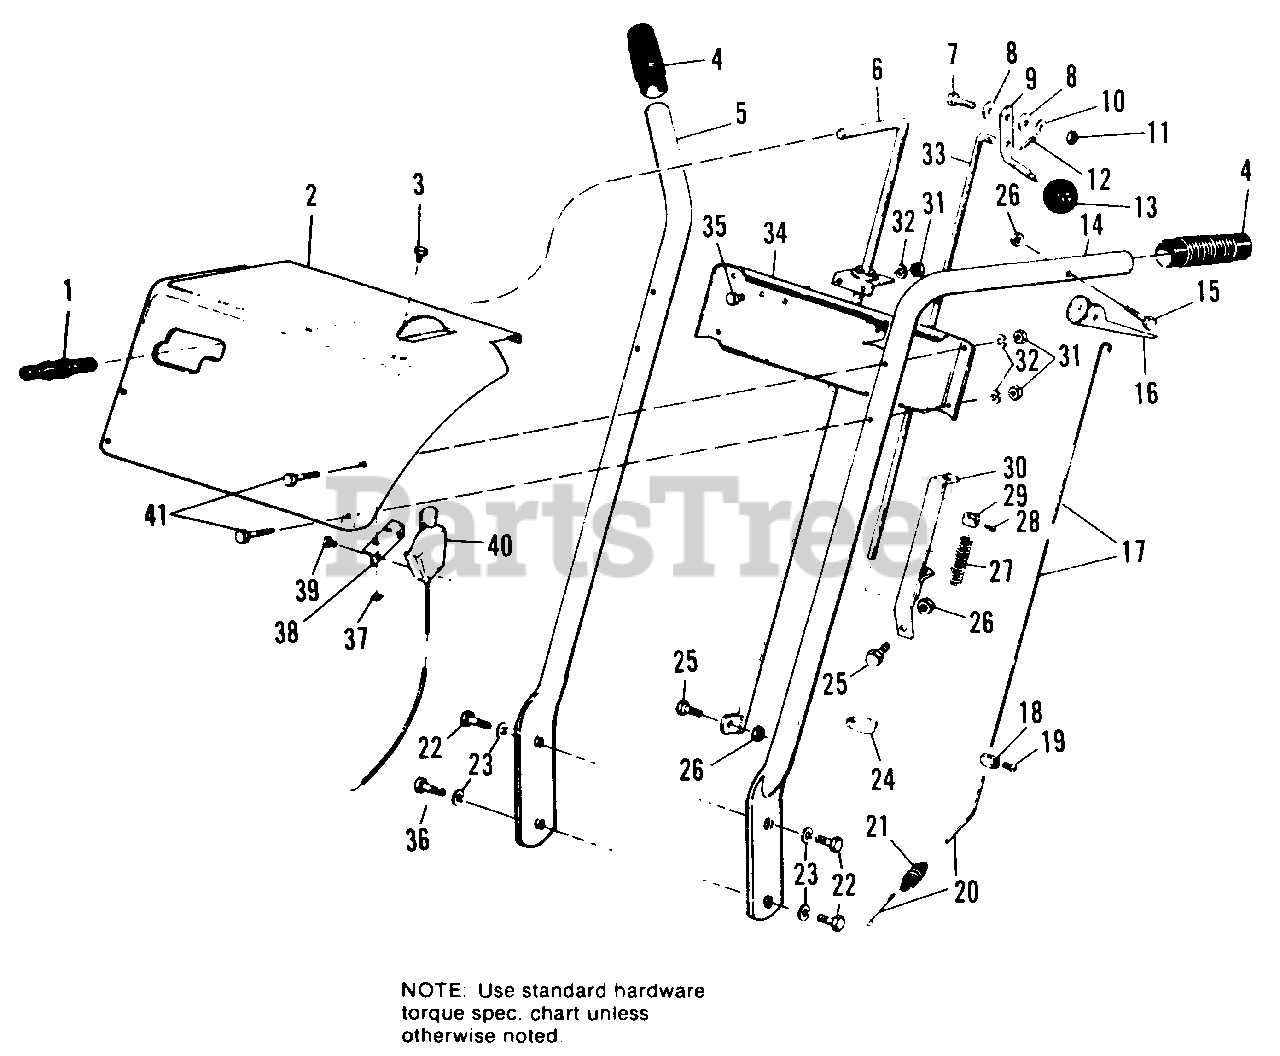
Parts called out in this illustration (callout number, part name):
1	GRIP, Handle
2	HOUSING ASSY., Control (990372 & 990430 Only)
2	HOUSING ASSY., Control (990560 Only)
3	SCREW, Self Tapping, #10 x 1/2 (990372 & 990430 Only)
3	SCREW, Self Tapping, 1/4 x 20 x 1/2 (990560 Only)
5	HANDLE, R.H. (990430 & 990560 Only)
5	HANDLE, R.H. (990372 Only)
6	ROD ASSY., Shift
7	CAPSCREW, Hex, 5/16-18 x 7/8
8	WASHER, Nylon
9	HANDLE, Clutch
10	WASHER, Plain, 1/4
11	LOCKNUT, Hex, W/Nylon Insert, 5/16-18
12	PIN, Cotter, 3/32 x 3/4
14	HANDLE, L.H. (990430 & 990560 Only)
14	HANDLE, L.H. (990372 Only)
15	CAPSCREW, Hex, 1/4-20 x 1-3/4
16	GRIP, Clutch
17	EXTENSION, Spring
18	CLAMP, Wire
19	SCREW, Rd. Hd., #10-24 x 3/8
20	EXTENSION, Wire
22	CAPSCREW, Hex, 5/16-16 x 7/8 (990430 & 990560 Only)
22	CAPSCREW, Hex, 3/8-16 x 7/8 (990372 Only)
23	LOCKWASHER, 5/16 (990430 & 990560 Only)
23	LOCKWASHER, 3/8 (990372 Only)
24	CLIP, Cable
25	CAPSCREW, Hex, 1/4-20 x 1
26	LOCKNUT, Hex, 1/4-20
28	SETSCREW, 1/4-20 x 3/8
29	COLLAR, Set
30	GUIDE ASSY., Rod
31	NUT, Hex, Full, 1/4-20
32	LOCKWASHER, 1/4
33	ROD, Clutch
34	COVER, Handle
35	CAPSCREW, Hex, 1/4-20 x 1/2
36	CAPSCREW, Hex, 5/16-18 x 1-1/2 (990430 & 990560 Only)
37	NUT, Speed
38	SUPPORT, Throttle
39	SCREW, Self Tapping, #10-24 x 1/2
40	CONTROL ASSY., Throttle (990372 & 990430 Only)
40	CONTROL ASSY., Throttle (990560 Only)
41	CAPSCREW, Hex Hd., 1/4-20 x 1-1/2
